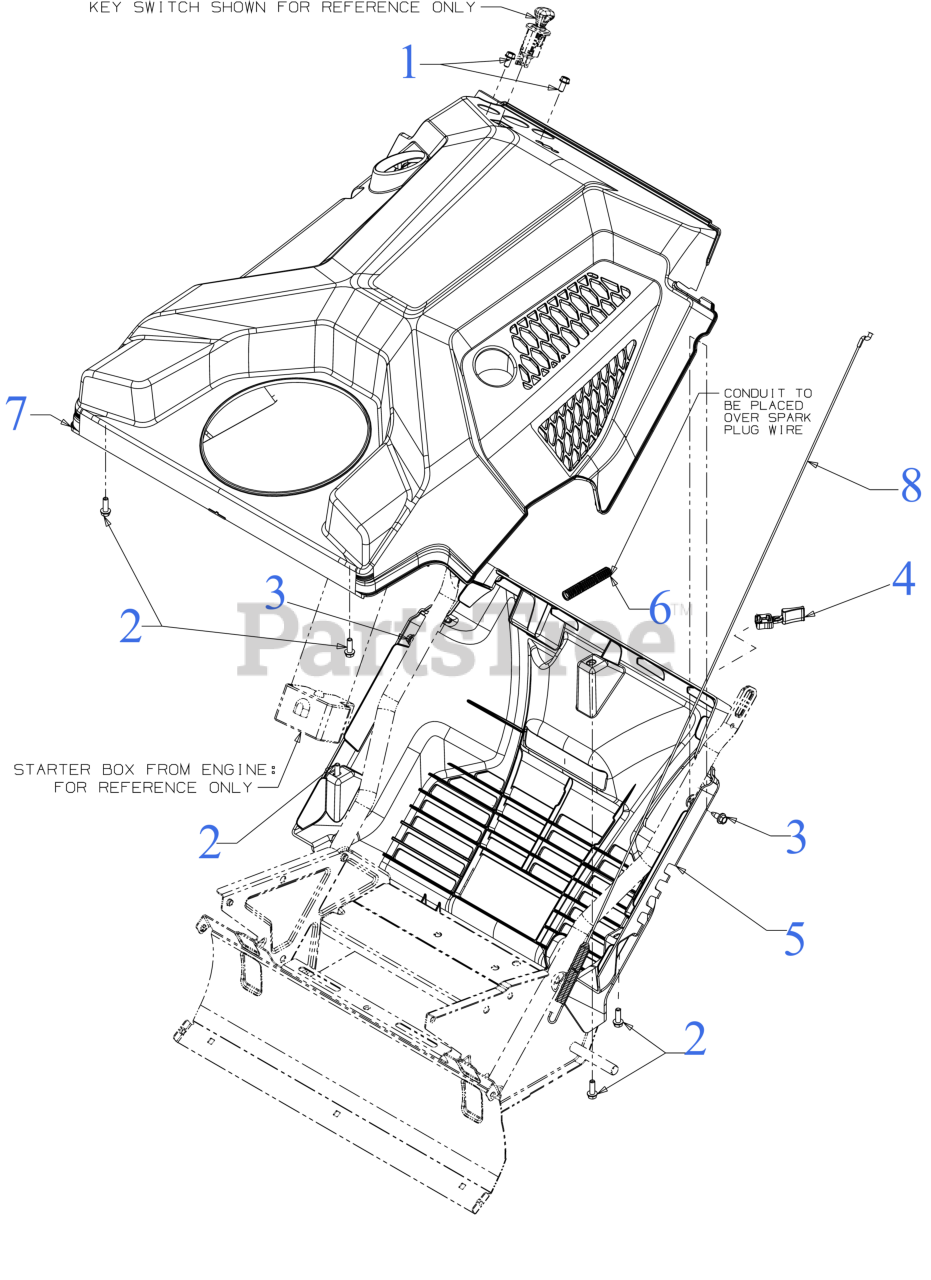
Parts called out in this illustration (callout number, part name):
1	HEX SCREW 1/4-15 x .50
2	SCREW 1/4-15 x .750
3	SCREW 1/4-20X.625
4	CHOKE EXTENION LEVER
5	BOTTOM COVER
6	CONVOLUTED CONDUIT
7	COVER (G-STYLE)
8	AUGER CLUTCH CABLE 37.05"
